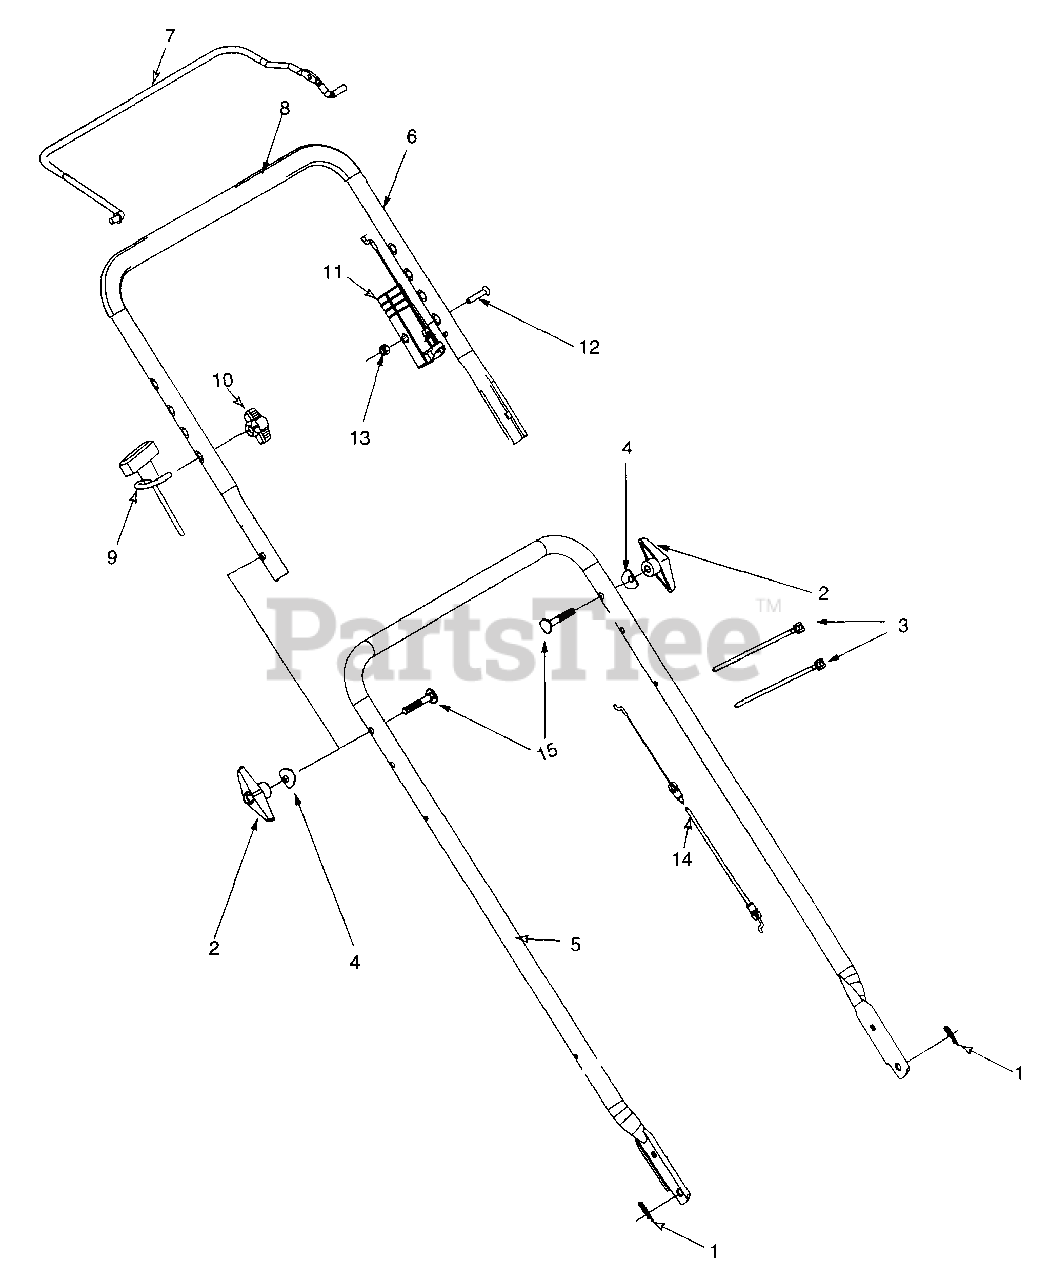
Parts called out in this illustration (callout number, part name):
1	Hairpin Clip
2	Wing Nut
3	Cable Tie
4	Saddle Washer
8	Foam Grip
9	Rope Guide
10	Handle Knob
11	Control Cable Box
12	Oval C-Sunk Scr.
13	Hex L-Nut 1/4-20 Thd.
14	Control Cable
15	Carriage Bolt
